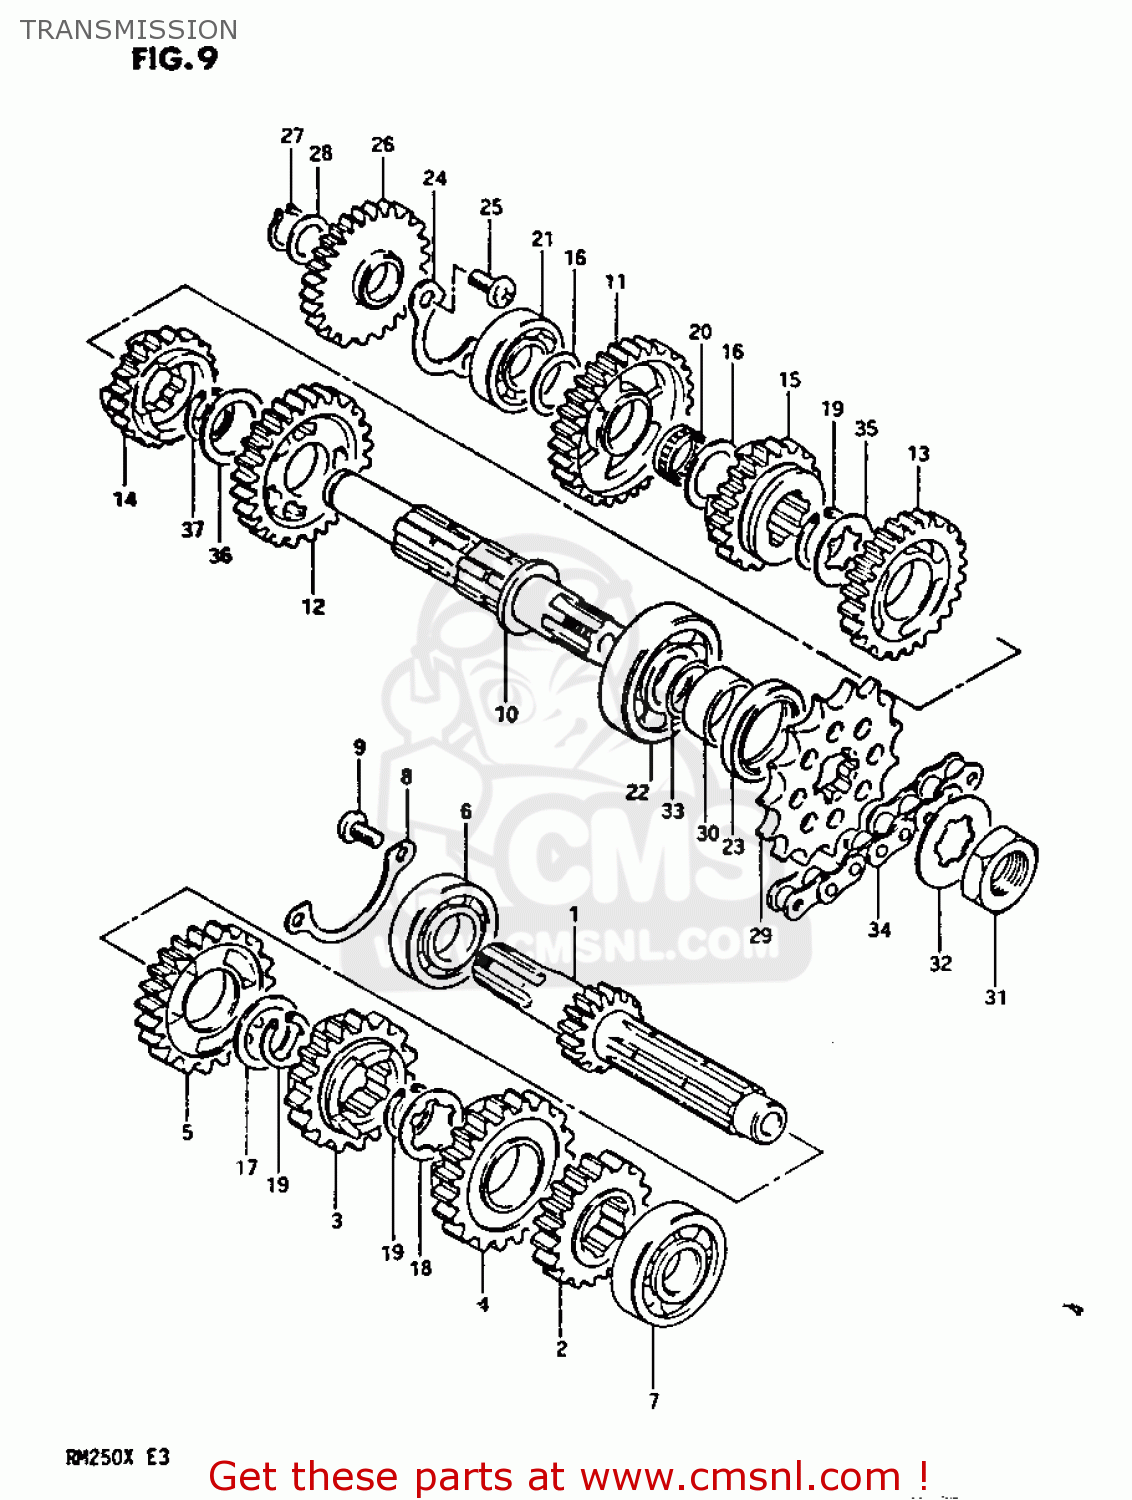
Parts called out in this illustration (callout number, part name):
1	SHAFT,COUNTER
2	GEAR,SECOND DRIVE
3	GEAR,THIRD DRIVE
4	GEAR,FOURTH DRIVE
5	GEAR,FIFTH DRIVE
6	BEARING(20X52X15)
7	BEARING(17X40X12)
8	PLATE,COUNTERSHAFT BEARING
9	SCREW 6X12
10	SHAFT,DRIVE
11	GEAR,1ST DRIVEN(NT:27)
12	GEAR,SECOND DRIVEN
13	GEAR,THIRD DRIVEN
14	GEAR,FOURTH DRIVEN
15	GEAR,FIFTH DRIVEN
16	WASHER
17	SHIM(22X28X0.5)
18	WASHER,LOCK
19	CIRCLIP
20	BEARING(17X21X9.8)
21	BEARING(17X40X12)
22	BEARING
23	SEAL,OIL(32X42X6)
24	PLATE,DRIVESHAFT BEARING
25	SCREW
26	GEAR,KICK STARTER IDLE
27	CIRCLIP
28	WASHER
29	SPROCKET,ENGINE (NT:14)
30	SPACER(22X32X11.5)
31	NUT
32	WASHER,LOCK
33	O RING(D:1.7,ID:22)
34	CHAIN ASSEMBLY,DRIVE
35	WASHER,LOCK
36	SHIM
37	CIRCLIP
